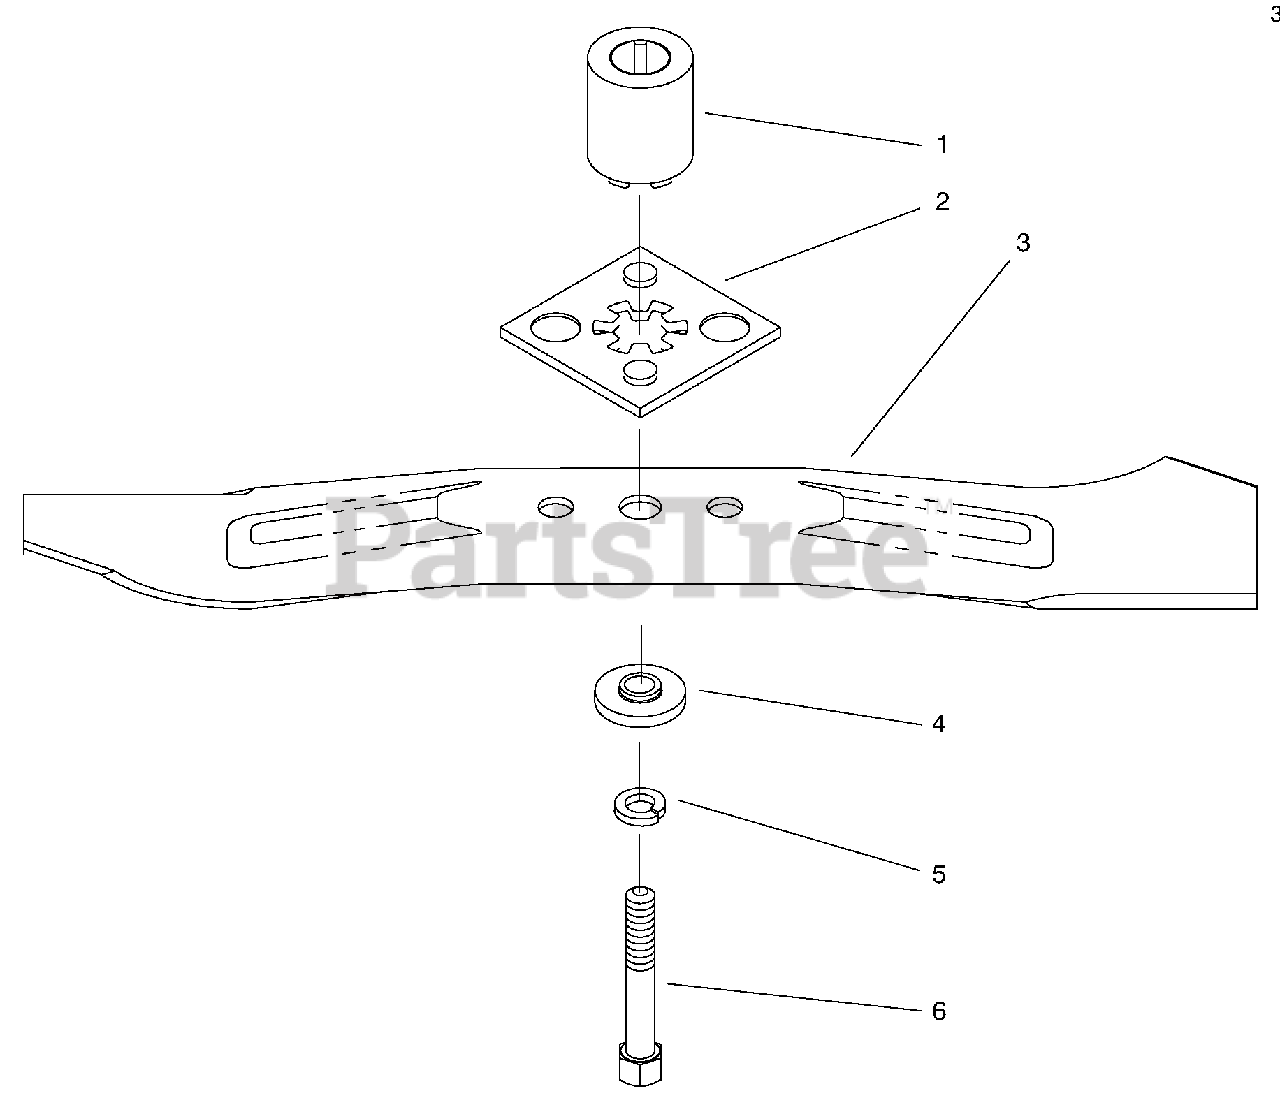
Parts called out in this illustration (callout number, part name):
1	Hub-Blade Driver
2	Plate-Blade Driver
3	Blade-48cm
4	Spacer-Blade
5	Washer-Lock
6	Bolt-Blade
